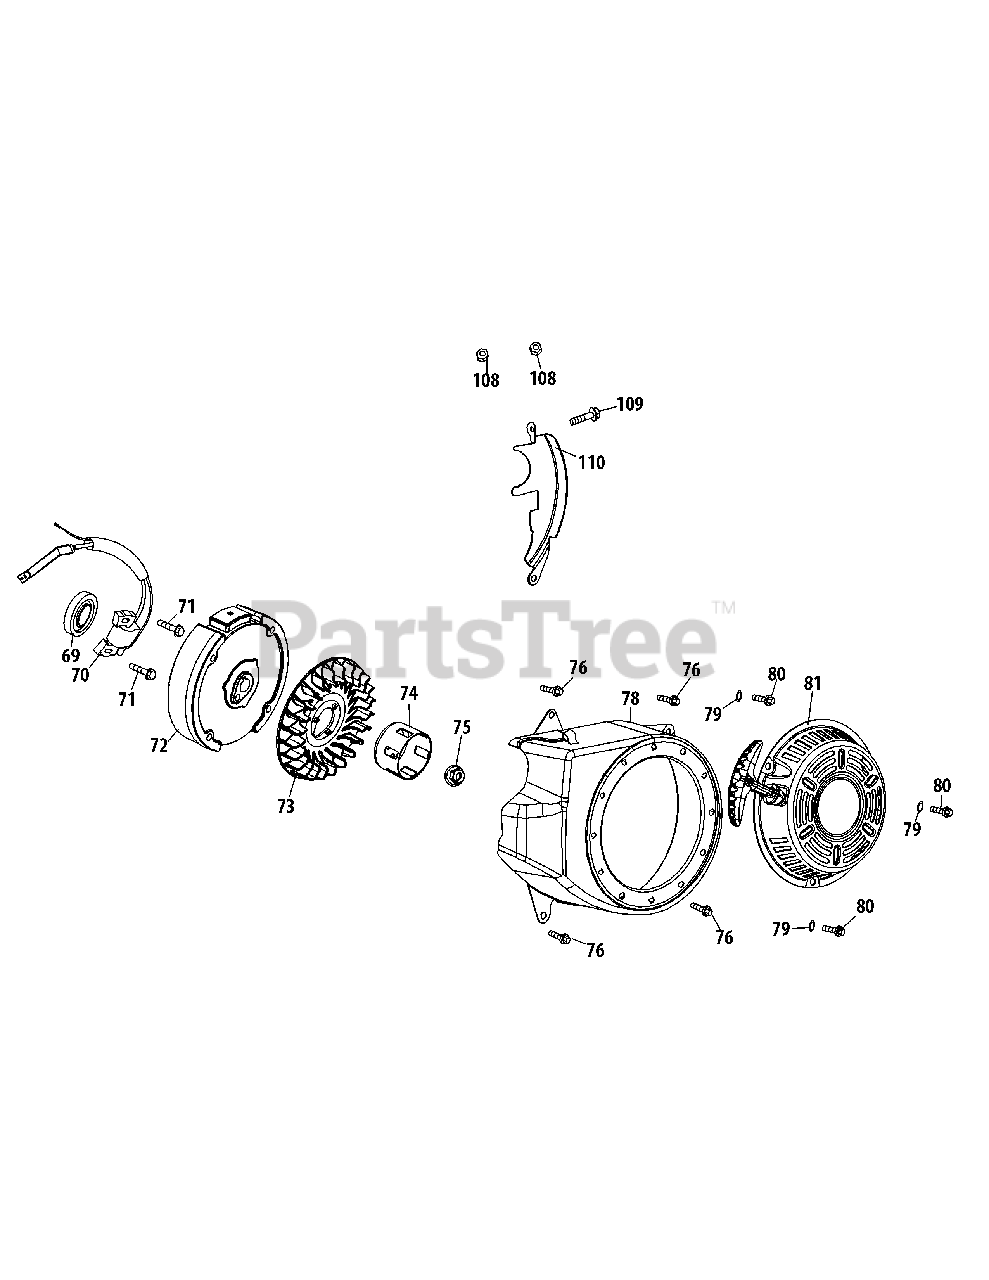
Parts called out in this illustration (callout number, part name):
69	Oil Seal, 25×?41.25×6
70	Ignition Coil Assembly
71	Bolt M6×25
72	Flywheel
73	Fan - Cooling
74	Starter Cup
75	Nut Special M14×1.5
76	Bolt M6×12
78	Blower Housing
79	Washer, Flat
80	Bolt M6×10
81	Recoil Starter
108	Nut, M6
109	Bolt M6×20
110	Blower Housing Shield
